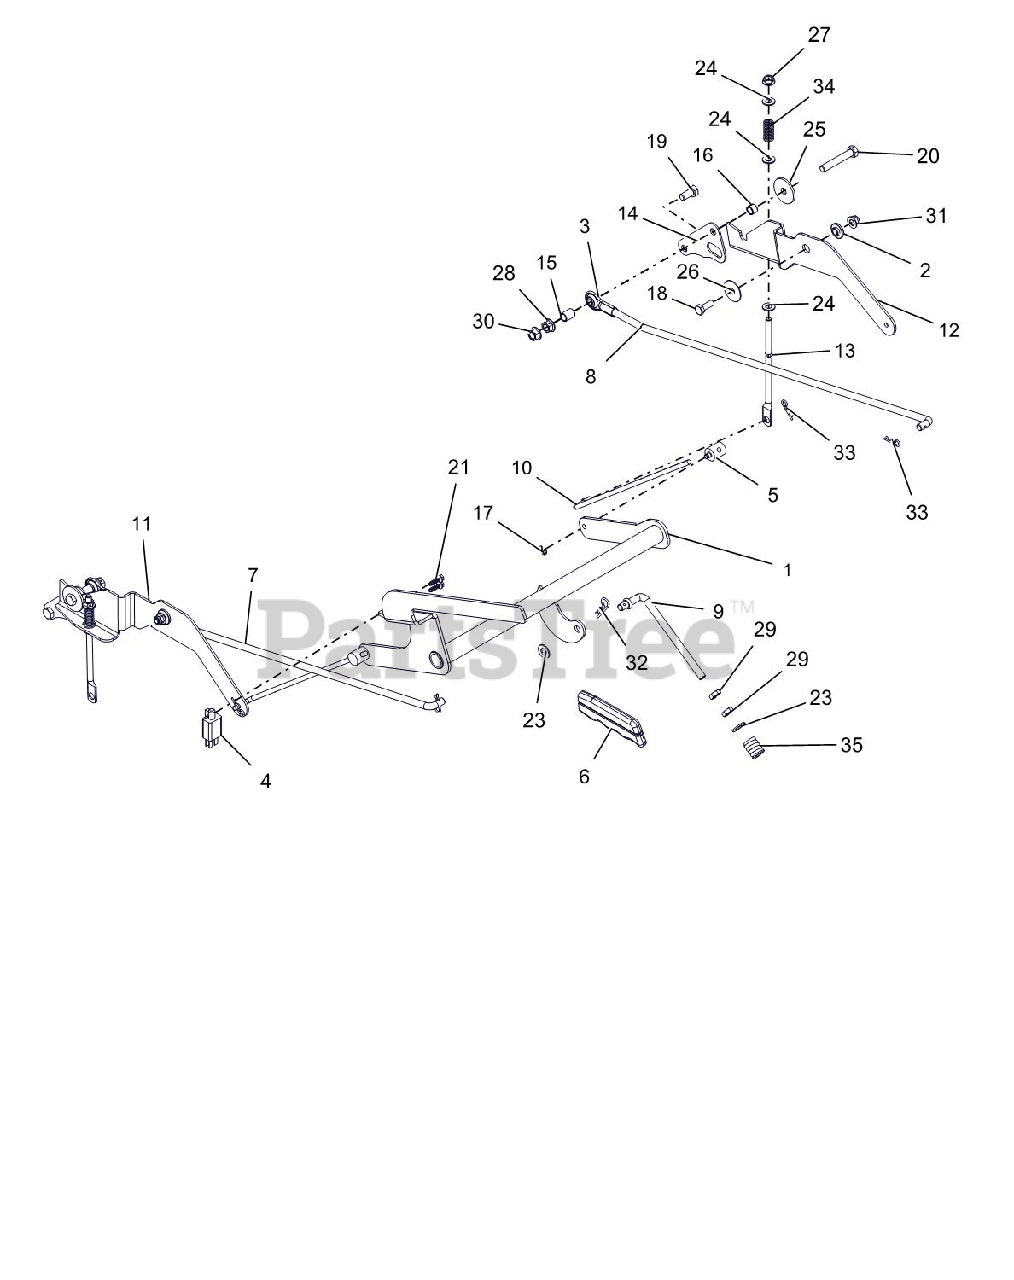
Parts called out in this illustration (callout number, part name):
1	WLDMT, BRAKE LEVER
2	BSHG, FLG .325X.499X.26X.88
3	ROD END, .38 RH
4	SWITCH- DOUBLE POLE N.O./N.O.
5	TRUNION, 1/4-20
6	GRIP, PARKING BRAKE (YELLOW)
7	STEERING, LINKAGE RH
8	STEERING, LINKAGE LH
9	LINK, OVER CENTER, PARKING BRK
10	LINK, BRAKE ARM
11	INTERLOCK, RH BRAKE LINK
12	INTERLOCK, LH BRAKE LINK
13	LINK, BRAKE COG
14	PLATE, TRANSAXLE ADAPTOR
15	SPCR, SLV .385X.500X.652
16	SPCR, SLV .385X.500X.350
17	RG-RTNG-EXT .250X.025
18	BOLT-HEX.31-18X.875 YWZC GR5
19	@BLT-HEX .38-16X.75 GR5 YWZC
20	@BLT-HEX .38-16X2.25 GR5 YWZC
21	SCR-TAP #12X.75 BOSS INDHXHD
23	@WSHR-FL-STL.406X.812X.065 YWZ
24	@WSHR-FL-STL.344X.688X.065YWZC
25	WSHR-FL-STL .380X1.50X.125YWZC
26	WSHR-FL-STL .347X1.254X.048YWZ
27	@NUT-LK-CTR-FLG .31-18 YZ GR F
28	NUT-LK-CTR-FLG .38-16 YWZC
29	NUT-HEX-JAM .375-16 YWZC
30	@NUT-LK-TOP-FLG .38-16 YWZC
31	@NUT-LK-NYL-FLG .31-18 YWZC
32	PIN-HAIR CTR .09 X 1.50 YWZC
33	PIN-HAIR INT .08X.18X1.18 YWZC
34	SPRING, COMPRESSION
35	SG-COMP .187X.56X1.62
